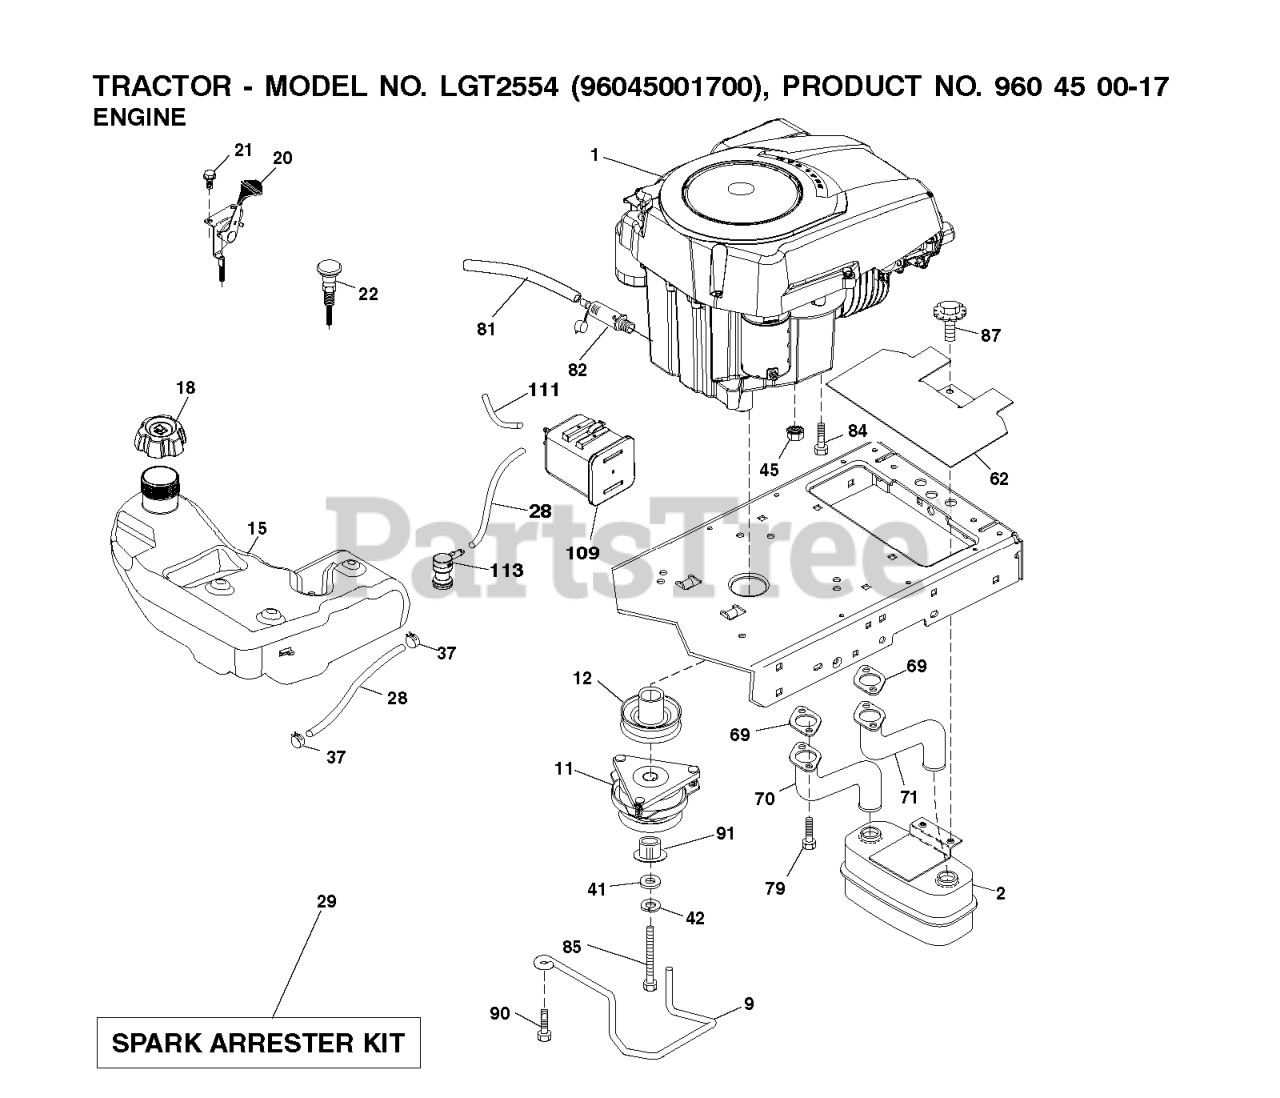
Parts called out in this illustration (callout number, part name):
2	MUFFLER.TWIN.CYL.LOW.TONE
9	KEEPER.BELT.ENGINE.4.2
11	CLUTCH MZ ZTR GT.48/54"1.125"
12	PULLEY ENGINE
15	RP TANK.ASM.FUEL.4GA.CARB
18	CAP ASM
20	THROTTLE CONTROL
21	SCREW.#10 X 0.750.BOS
22	CONTROL.CHOKE.ERGO.PUSH-IN.BLA
28	LINE.FUEL.64"REAR.EMIS
29	KIT.SPARK ARRESTOR 794945 B&S
37	HOSE CLAMP
42	LOCKWASHER
45	NUT
62	RP SHIELD HEAT MUFFLER
70	RP.PIPE-EXHAUST LH
71	Tube Exhaust RH
79	SCREW.SOCKET HD.5/16-1
81	TUBE, DRAIN OIL ASM.
82	PLUG DRAIN OIL EASY
84	SCREW 3/8-16X1
85	BOLT HEX 7/16-20 X 3.75 GR. 5
87	BOLT.5/16-18UNCX1.W/SEMS.BLK
90	SCREW 3/8-16X1
91	BUSHING.1.375OD
109	CANNISTER, CARBON
111	RP PURGE LINE
113	VALVE.SLANT.CARTRDG.90 DEG.TEX
